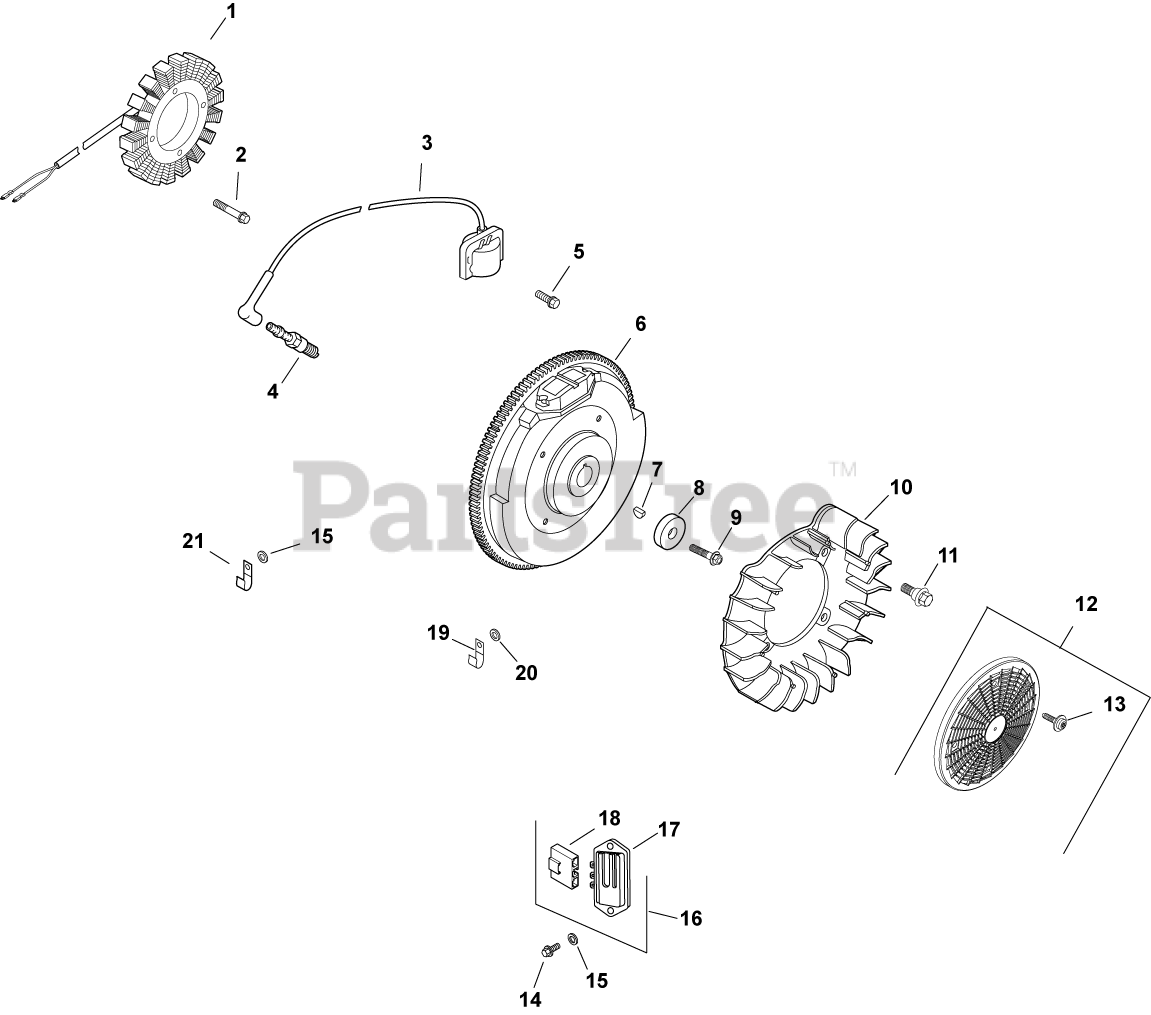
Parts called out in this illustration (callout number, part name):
1	KIT, 25 AMP STATOR ASSY.
2	SCREW, THD FROM M5X0.8X30
3	KIT, MODULE IGNTN (CDI FIXED)
4	PLUG, SPARK (PRO SERIES)
5	SCREW, FLG THD FRM M5X.8X20-(#25086399S)
6	FLYWHEEL, PAINTED-USE 24 025 55-S
7	KEY, 3/16" X 5/8"
8	WASHER, FLAT 13/32"
9	SCREW, FLG M10X1.5X45 - (#25086361S)
10	FAN USE 24 755 253-S
11	BOLT, SHOULDER
12	KIT, GRASS SCREEN
13	SCREW, FLG SEMS M4X.7X25
14	SCREW, PHL HD #11-16X7/8"
15	WASHER, FLAT 7/32"
16	KIT, FULL WAVE CONVERSION
17	REG/RECTIFIER (20/25 AMP)-USE 25 403 20-
18	CONNECTOR, BODY (KM)-USE 25 155 41-S
19	CLIP, TUBE & WIRING (KM)
20	WASHER, FLAT 1/4" (O.D. 1/2")
21	CLIP, CABLE
